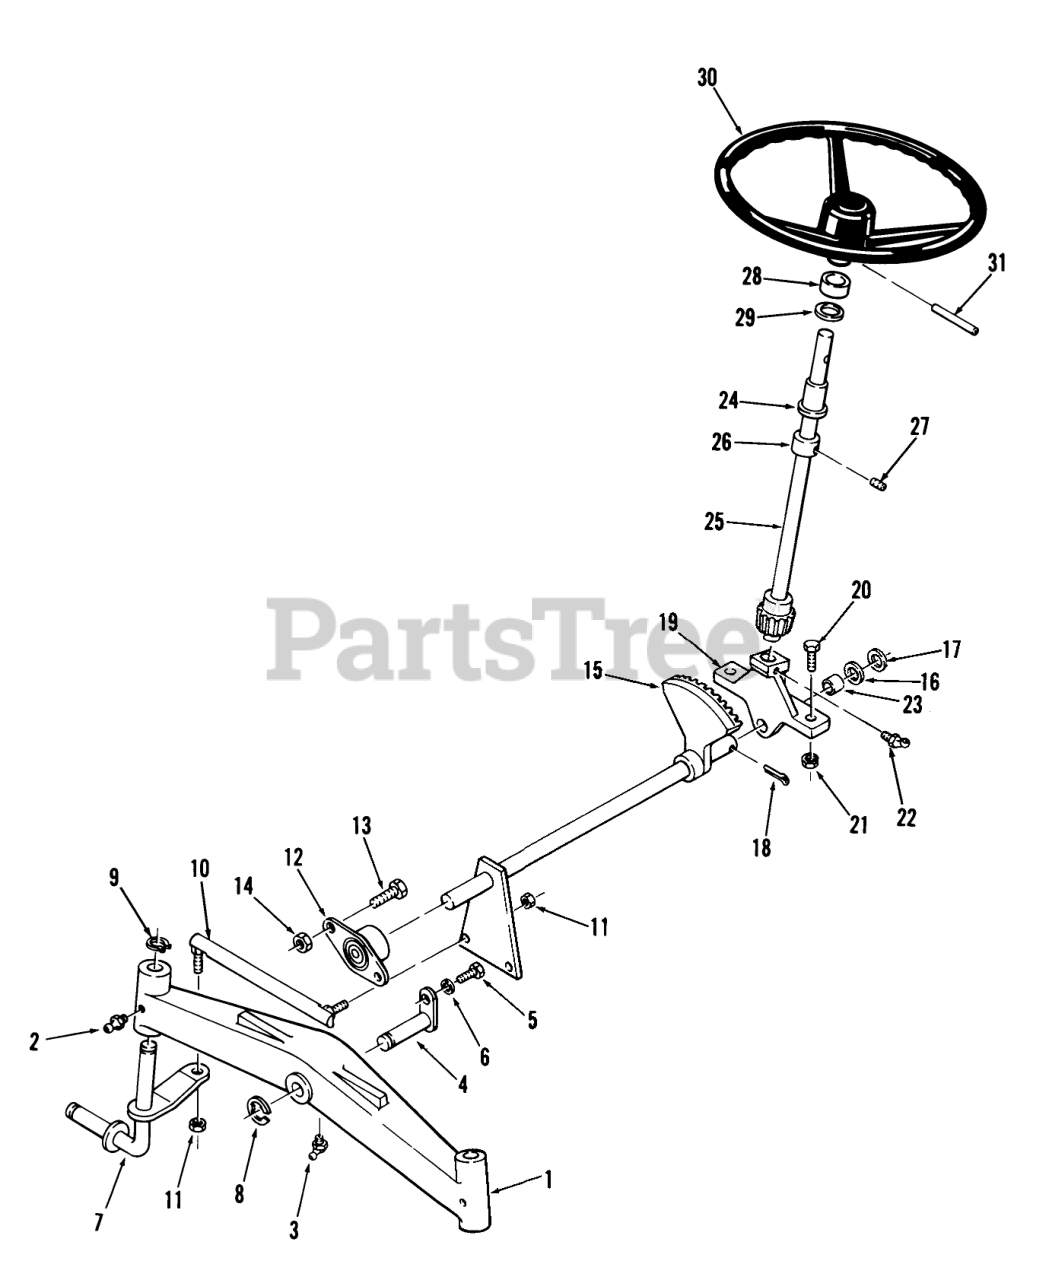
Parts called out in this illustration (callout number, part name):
1	AXLE-FRONT
2	Zerk
3	FITTING-GREASE
4	PIN AND PLATE ASM
5	H H C S
6	Lockwasher
7	Front Spindle RH
7	Front Spindle LH
8	E-RING
9	Snap Ring
10	Tie Rod RH
10	Tie Rod LH
11	NUT-6
12	BEARING-FLANGED
13	Bolt
14	Nut
15	Assy-Steering
16	WASHER-SHIM
17	WASHER
18	PIN-4
19	Support
20	BOLT
21	Nut
22	FITTING-GREASE
23	BEARING-BRONZE
24	BEARING
25	Upper Steering Shaft
25	Shaft-Upper Steering
26	Collar
27	SCREW-SET
28	COLLAR
29	WASHER-BOWED
30	STEERING WH 13" PLAS
31	Pin-Roll
